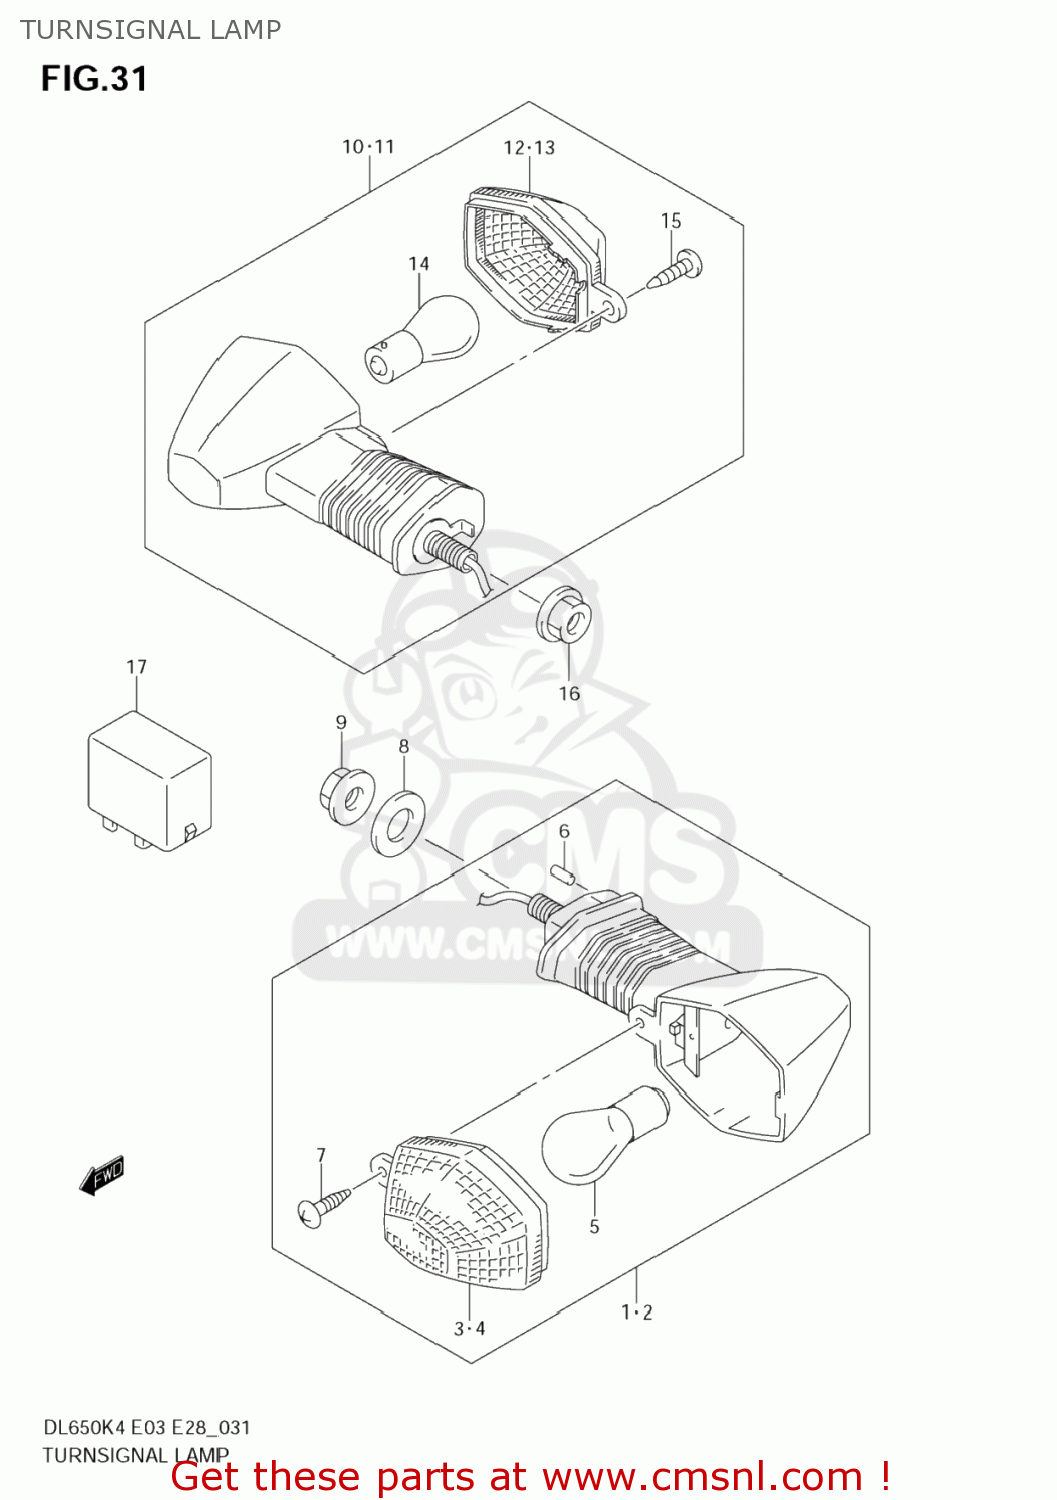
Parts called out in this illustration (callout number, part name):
1	LAMP ASSY,FR TURN SIGNAL,R
2	LAMP ASSY,FR TURN SIGNAL,L
3	LENS
4	LENS
5	BULB(12V21W)
6	PIN(4.5X9.5)
7	SCREW
8	WASHER(12.5X30X1.6)
9	NUT
10	LAMP ASSY,RR TURNSIGNAL,R
11	LAMP ASSY,RR TURNSIGNAL,L
12	LENS
13	LENS
14	BULB(12V21W)
15	SCREW
16	NUT
17	RELAY ASSY,TURNSIGNAL LAMP
